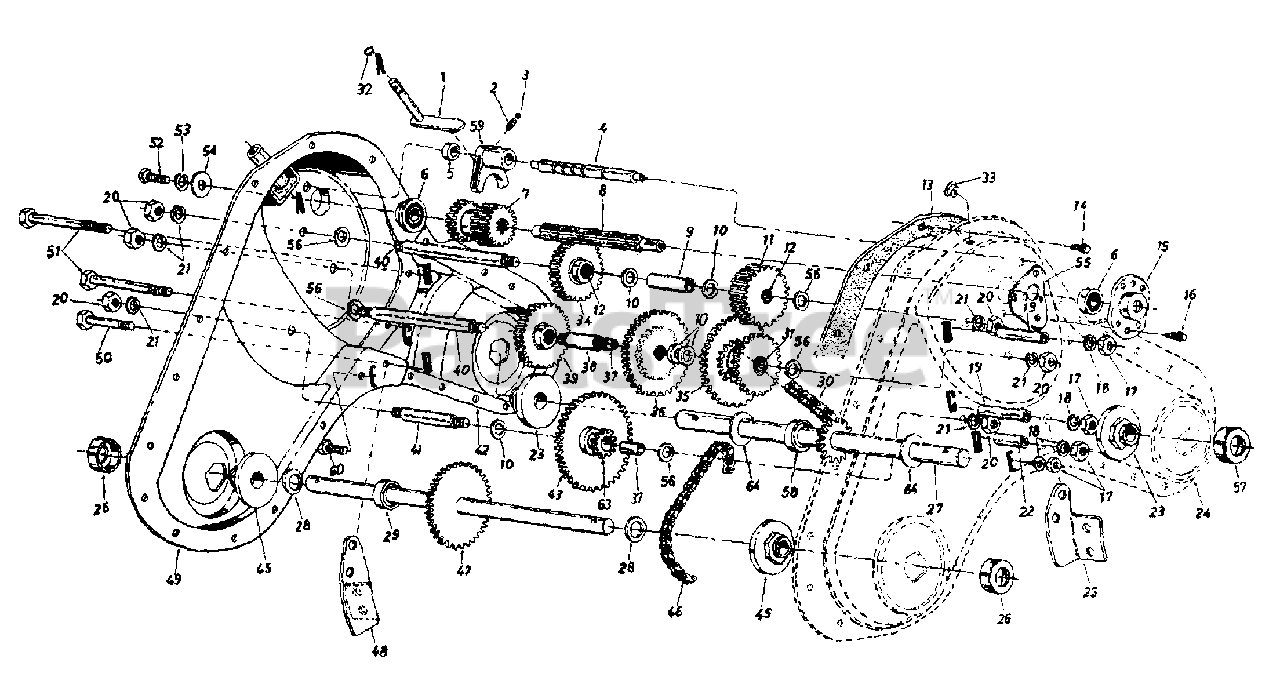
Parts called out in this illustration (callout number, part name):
1	Shifting Bracket Ass'y.
2	Compression Spring .50" Lg.
3	Ball Detent .250" Dia.
4	Detent Shaft 1/2" Dia.
5	Spacer .505" I.D. x .88" O.D.
6	Ball Brg. .62" I.D. x 1.38"
7	Spur Gear 16T (Input)
8	Input Spline Shaft 7/8"
9	Spacer .657" I.D. x 2.85" Lg.
10	Fl-Wash. .640" I.D. x 1.24"
11	Spur Gear 30T 7/8" I.D.
12	Needle Bearing 5/8" I.D.
13	Gasket - Trans. Hsg.
14	Hex S-Tap Scr. 1/4-20 x .5"
15	1-3/8" Dia. Bearing Housing
16	Hex TT-Tap Scr. 1/4-20 x .75"
17	Hex Nut 5/16-18 Thd.
18	L-Wash. 5/16" I.D.
19	Spacer 1.56" Lg.
20	Hex Nut 7/16-20 Thd.
21	Bell-Wash. .45" I.D. x 1.0"
22	Spacer 1.015" Lg.
23	Tine Shaft Brg. 1.002 x 2.50
27	Tine Shaft Ass'y. 1" O.D.
28	Fl-Wash. .76" I.D. x 1.5" O.D.
29	Spacer .75" I.D. x .50" Lg.
30	Chain #50 5/8 Pitch x 52 Links - Endless
31	Needle Bearing 5/8" I.D.
32	Snap Ring
33	Taper Cap Plug
34	Spur Gear 30T 12/16" I.D.
35	30/44T Gear Ass'y. Comp.
36	Spur Gear 44T/11T
37	Sleeve Bearing
38	Gear Hub 3/4" I.D. x 3" Lg.
39	Spur Gear 30T 1.0" I.D. x 1/2" W
40	Jack Shaft 5/8" Dia. x 5"
41	Jack Shaft 5/8" Dia. x 2.38"
45	Wheel Brg. .752" x 2.5"
46	#420 Chain 1/2 Pitch x 50 Links -
47	Wheel Shaft Ass'y. 15.6"
51	Hex Bolt 5/16-18 x 2.5"
52	Hex Bolt 1/4-20 x .62" Lg.
53	L-Wash. 3/8" I.D.
54	Fl-Wash. 1/4" I.D. x .93" O.D.
55	Gear Positioner Bracket
56	Fl-Wash. 7/16" I.D. x 1-3/8"
57	Seal 1" Shaft
58	Spacer 1" I.D. x 2" O.D.
59	Shifting Fork
60	Hex Bolt 5/16-18 x 1" Lg.
63	10T Sprocket Ass'y.
64	Thrust Wash. 1.03" I.D. x 1.62" O.D.
